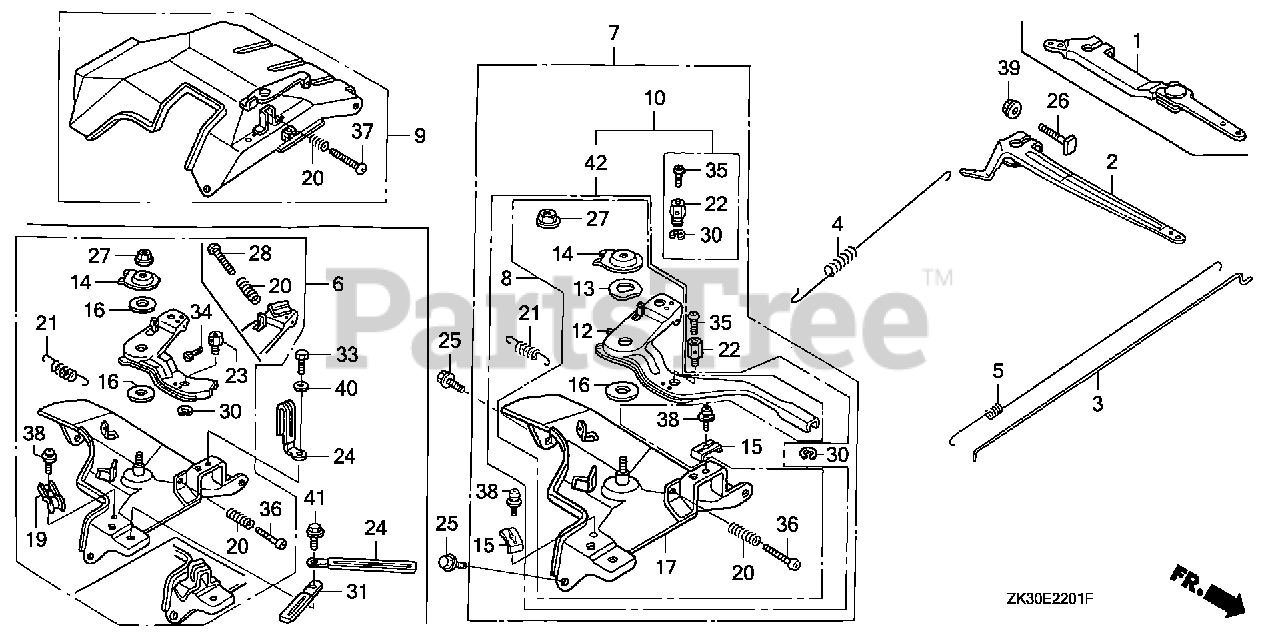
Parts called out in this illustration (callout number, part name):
2	ARM, GOVERNOR
3	ROD, GOVERNOR
4	SPRING, GOVERNOR (L=137.5MM)
5	SPRING, THROTTLE RETURN
12	LEVER, CONTROL
13	SPRING, LEVER
14	WASHER, CONTROL LEVER
15	HOLDER, CABLE
16	SPACER, CONTROL LEVER
17	BASE, CONTROL
20	SPRING, CONTROL ADJUSTING
21	SPRING, CABLE RETURN
25	BOLT, FLANGE (6X12) (CT200)
26	BOLT, GOVERNOR ARM
27	NUT, SELF-LOCK (6MM)
36	SCREW, PAN (5X32)
38	SCREW, PAN (5X16)
39	NUT, FLANGE (6MM)
42	CONTROL ASSY. (REMOTE)
